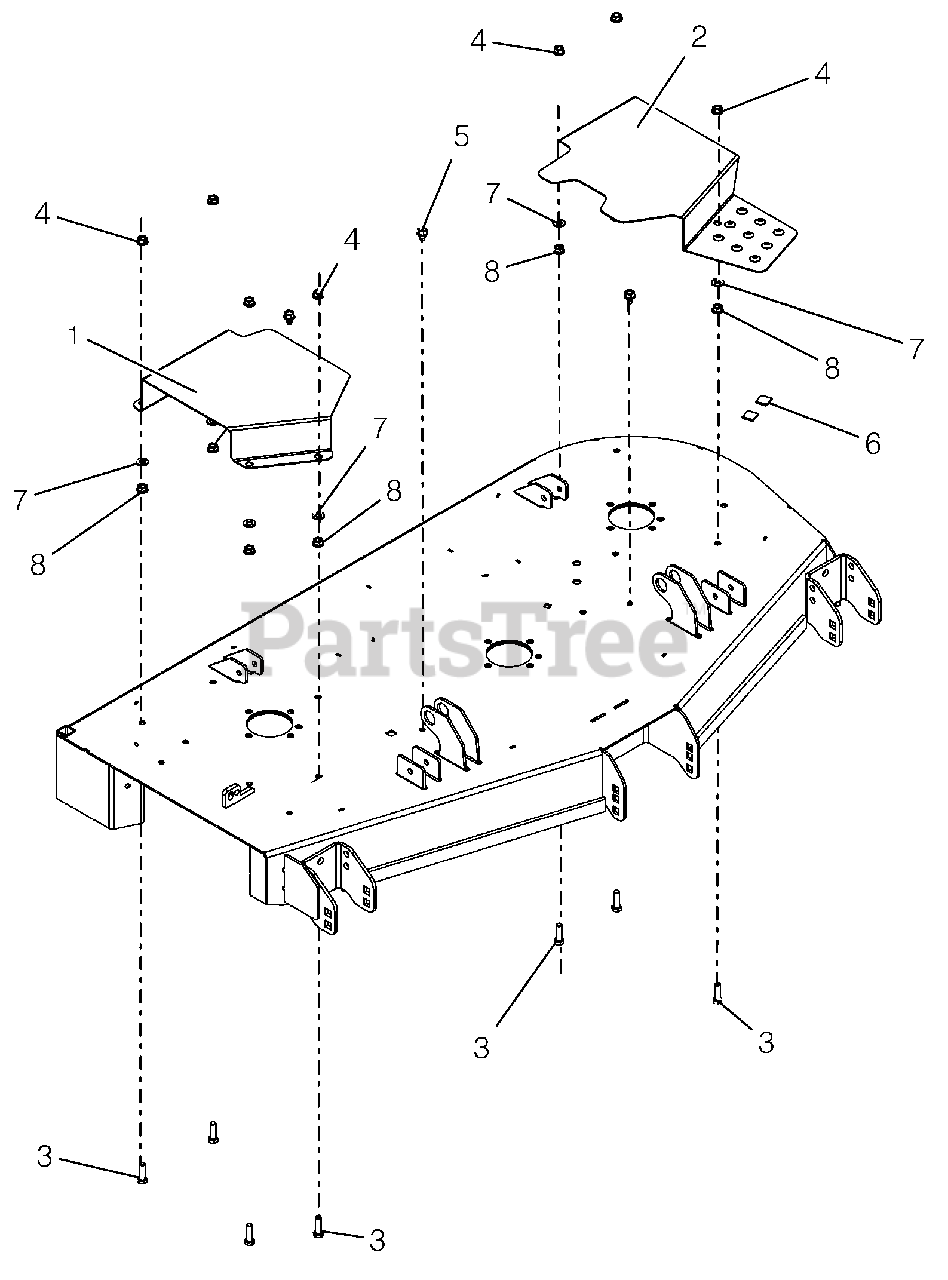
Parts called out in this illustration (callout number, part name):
1	COVER, BELT 52" & 60" RIGHT
2	COVER, BELT 52" LEFT
3	@BLT-HEX .38-16X1.25 GR5 YWZC
4	@NUT-SPNLK-FLG .375-16 YWZC
5	@SCR-TAP .38-16X.50 HWH TR YWZ
7	@WSHR-FL-STL.406X.812X.065 YWZ
8	@NUT-SPNLK-FLG .375-16 YWZC
